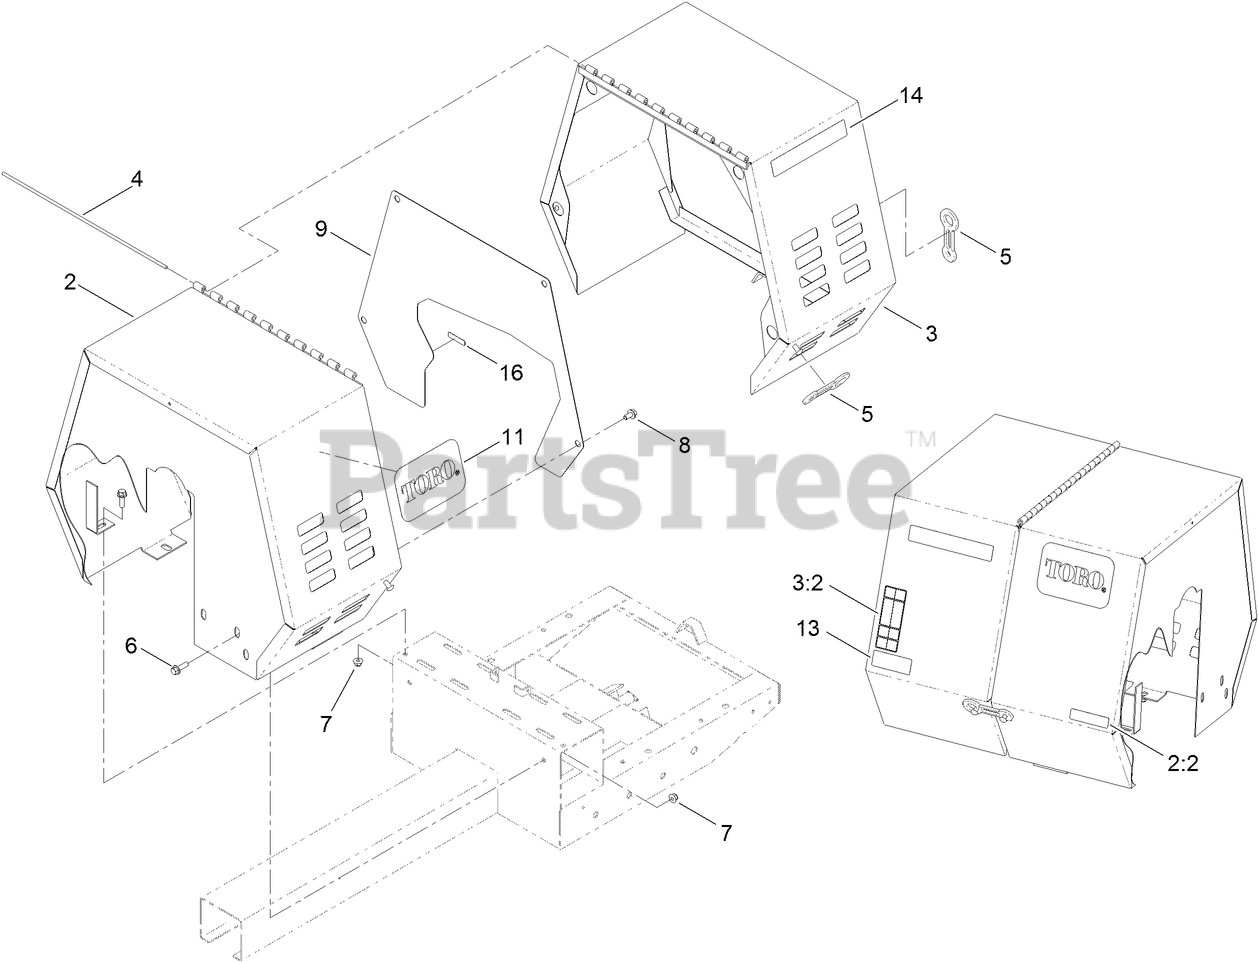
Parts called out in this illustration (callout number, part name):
2	STATIONARY COWL ASM
2:2	DECAL-ARRESTER, SPARK
3	MOVABLE COWL ASM
3:2	DECAL-WARNING
5	LATCH-RUBBER
6	SCREW-HHF
7	NUT-HF, NI
8	SCREW-HWH
9	PLATE-ACCESS, BELT
11	DECAL
14	DECAL-MM-658H
16	DECAL-GREASE
